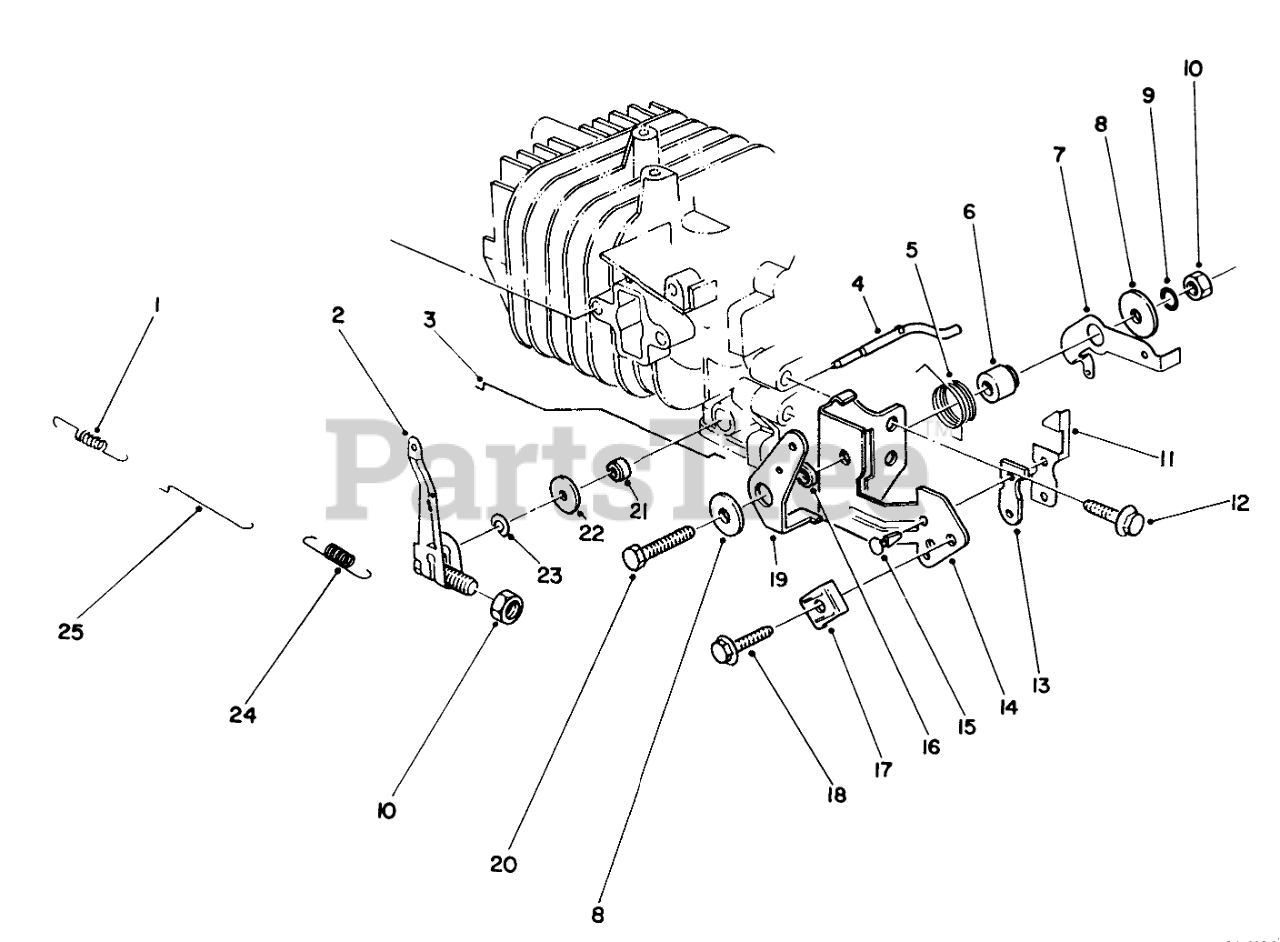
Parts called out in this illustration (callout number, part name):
1	SPRING
2	ARM-GOVERNOR
3	ROD-CHOKE
4	Shaft-Govemor
5	SPRING-CHOKE LEVER
6	Gov Lever Spacer
7	LEVER-SPRING, GOVERNOR
8	WASHER
9	LOCKWASHER
11	TERMINAL-KILL SWITCH
13	INSULATOR-KILL SWITCH
14	BRACKET-THROTTLE, CONTROL
15	KILL SWITCH RIVET
16	SPACER-CHOKE LEVER
17	CLAMP
19	LEVER-CONTROL, CHOKE
21	SEAL-OIL
22	WASHER
23	E-RING
24	SPRING-GOVERNOR
25	ROD-CARBURETOR
